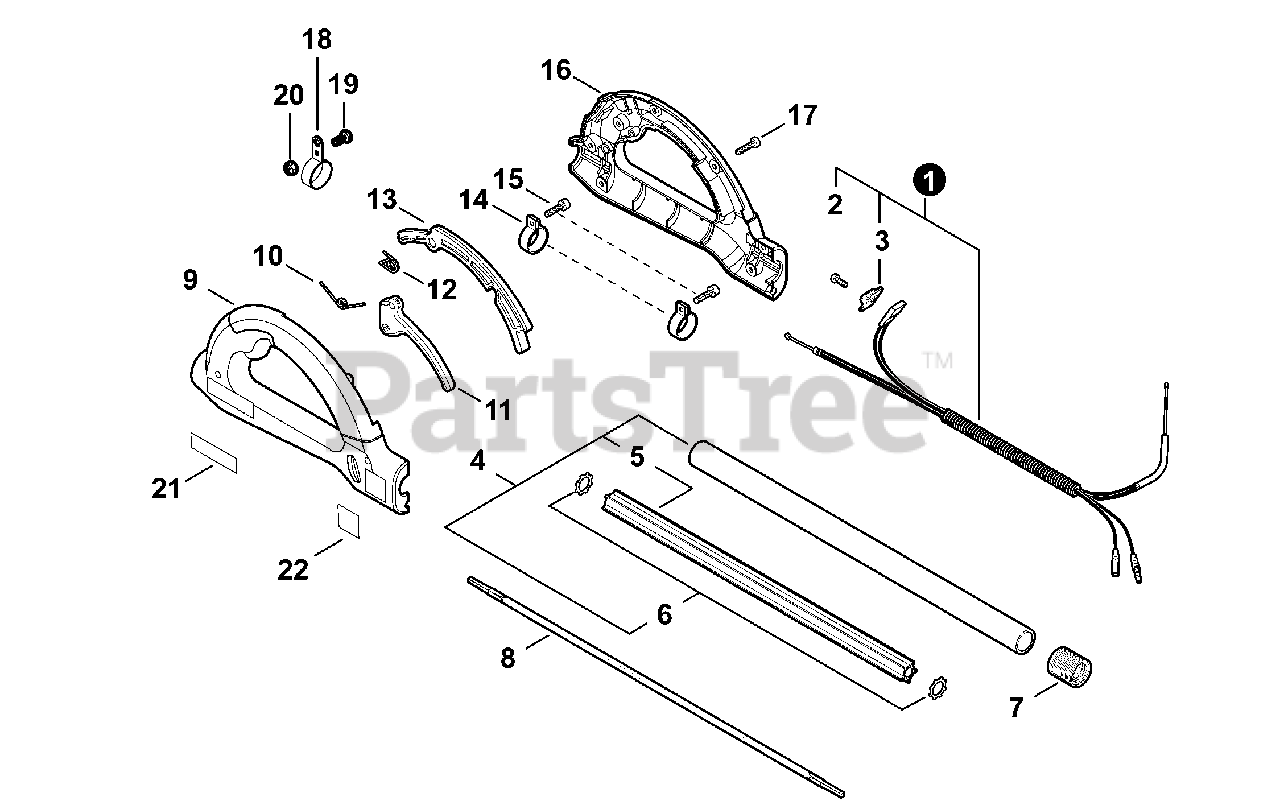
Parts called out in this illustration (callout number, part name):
1	CABLE ASSY, CONTROL
2	SCREW 3×10
3	KNOB, SWITCH - ORANGE
4	MAIN PIPE ASSY
7	TUBE, FLEXIBLE
8	DRIVESHAFT - FLEXIBLE
9	BODY, HANDLE - LEFT
10	SPRING, TORSION
11	TRIGGER, THROTTLE
12	SPRING, TORSION
13	LOCKOUT, THROTTLE
15	SCREW M5×20
16	BODY, HANDLE - RIGHT
17	SCREW M5×18
19	SCREW 5×10
20	NUT, M5×8 NYLON INSERT
21	LABEL, ECHO
22	LABEL, CAUTION
